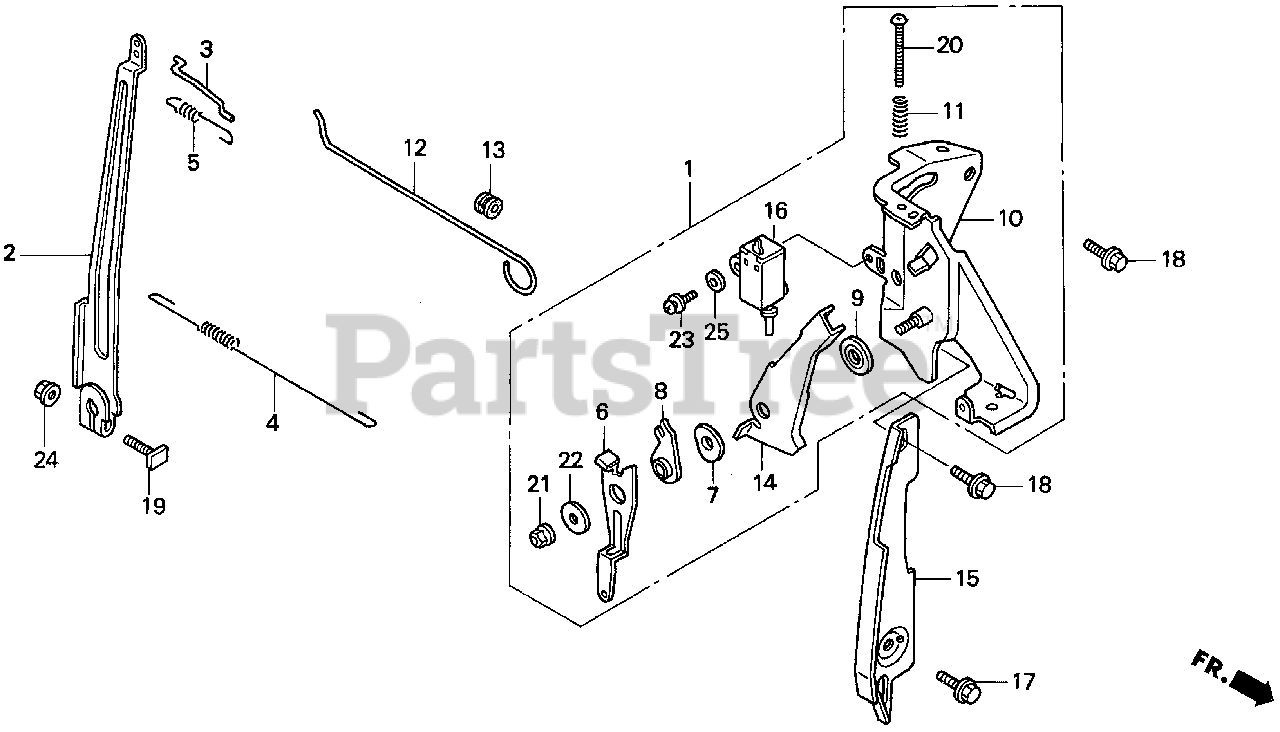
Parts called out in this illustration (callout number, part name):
1	CONTROL ASSY.
2	ARM, GOVERNOR
3	ROD, GOVERNOR
4	SPRING, GOVERNOR
5	SPRING, THROTTLE RETURN
6	LEVER, CONTROL
7	SPRING, LEVER
8	WASHER, CONTROL LEVER
9	SPACER, CONTROL LEVER
10	BASE, CONTROL
11	SPRING, CONTROL ADJUSTING
12	ROD, CHOKE CONTROL
13	GROMMET, CHOKE ROD
14	LEVER, STOP
15	PLATE, SIDE
16	SWITCH ASSY., ENGINE STOP (N.O)
17	BOLT, FLANGE (6X12) (CT200)
18	BOLT, FLANGE (6X14)
19	BOLT, GOVERNOR ARM
20	SCREW, ADJUST
21	NUT, SELF-LOCK (6MM)
22	WASHER, WHEEL (6MM)
23	SCREW-WASHER (4X12)
24	NUT, FLANGE (6MM)
25	WASHER, PLAIN (4MM)
